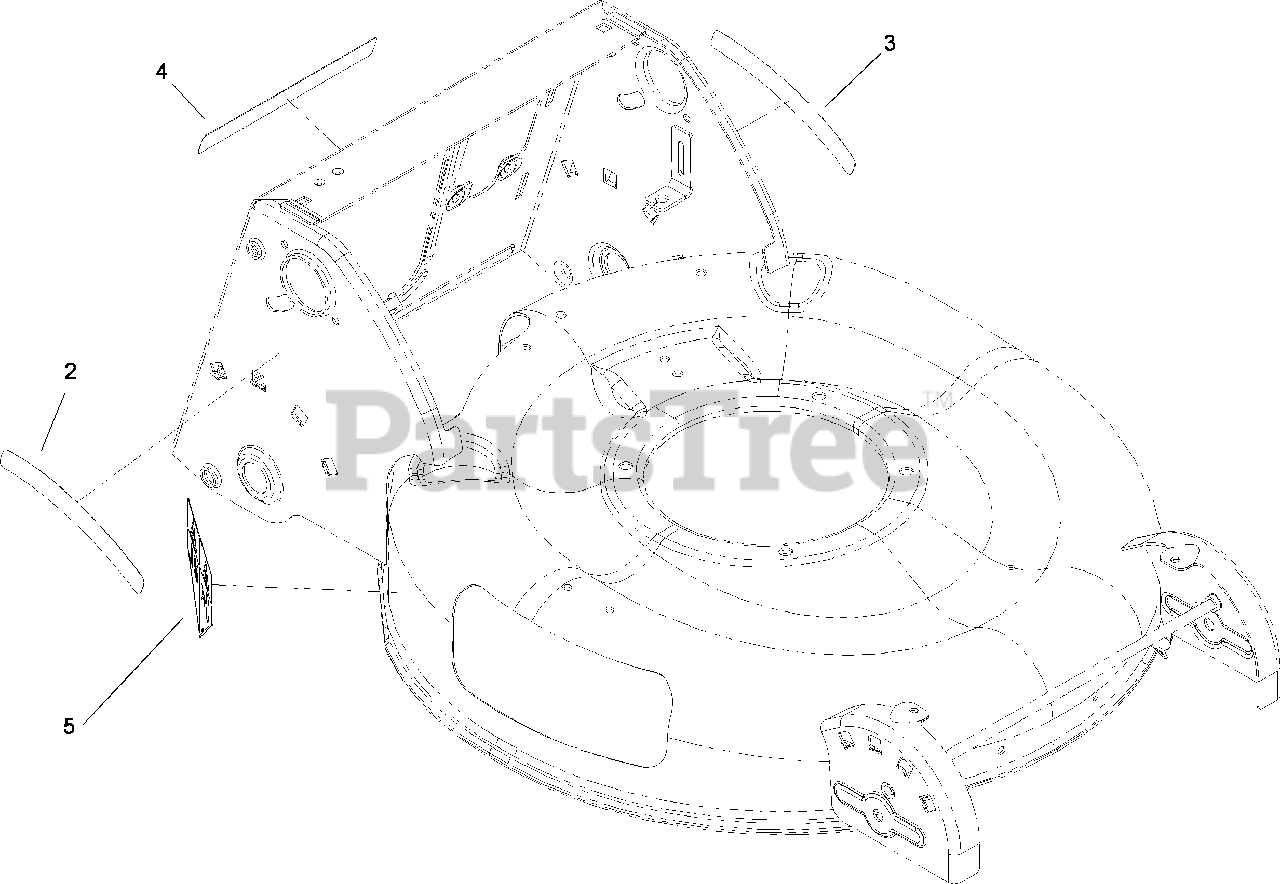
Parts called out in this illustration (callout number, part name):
2	DECAL-HOC, RH
3	DECAL-HOC, LH
4	DECAL-SAFETY, BAG
5	DECAL-DANGER
